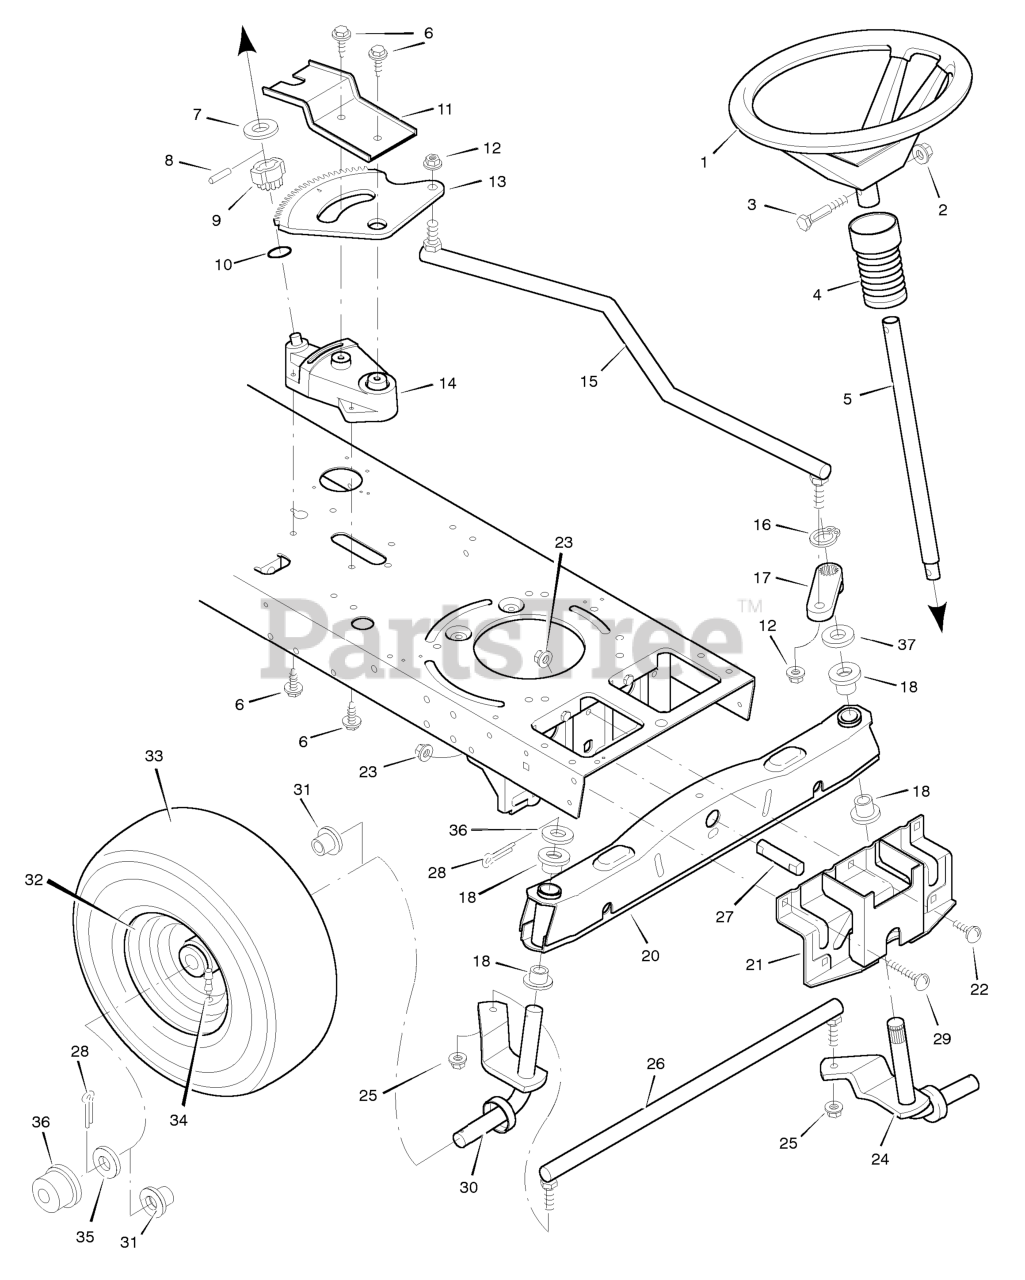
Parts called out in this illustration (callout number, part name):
1	Wheel, Steering
2	Nut, Hex
3	Bolt, Hex
4	Bellows
5	Post Assembly, Steering
7	Washer
8	Pin, Spring
9	Gear Assembly, Pinion
10	O-Ring
11	Clip, Gear Retainer
12	Locknut, Flange
13	Gear, Sector
14	Support, Steering
15	Link, Drag
17	Arm, Drag Link
18	Bearing
20	Axle Assembly (with grease fittings)
21	Hanger Assembly, Axle
22	Bolt, Carriage
23	Locknut, Flange
24	Spindle Assembly, Left
25	Locknut, Flange
26	Rod, Tie
27	Pin, Pivot
28	Pin, Cotter
29	Bolt, Carriage
30	Spindle Assembly, Right
31	Bearing, Wheel
32	Wheel & Tire Assembly
33	Tire *
34	Stem, Valve
36	Hub Cap
